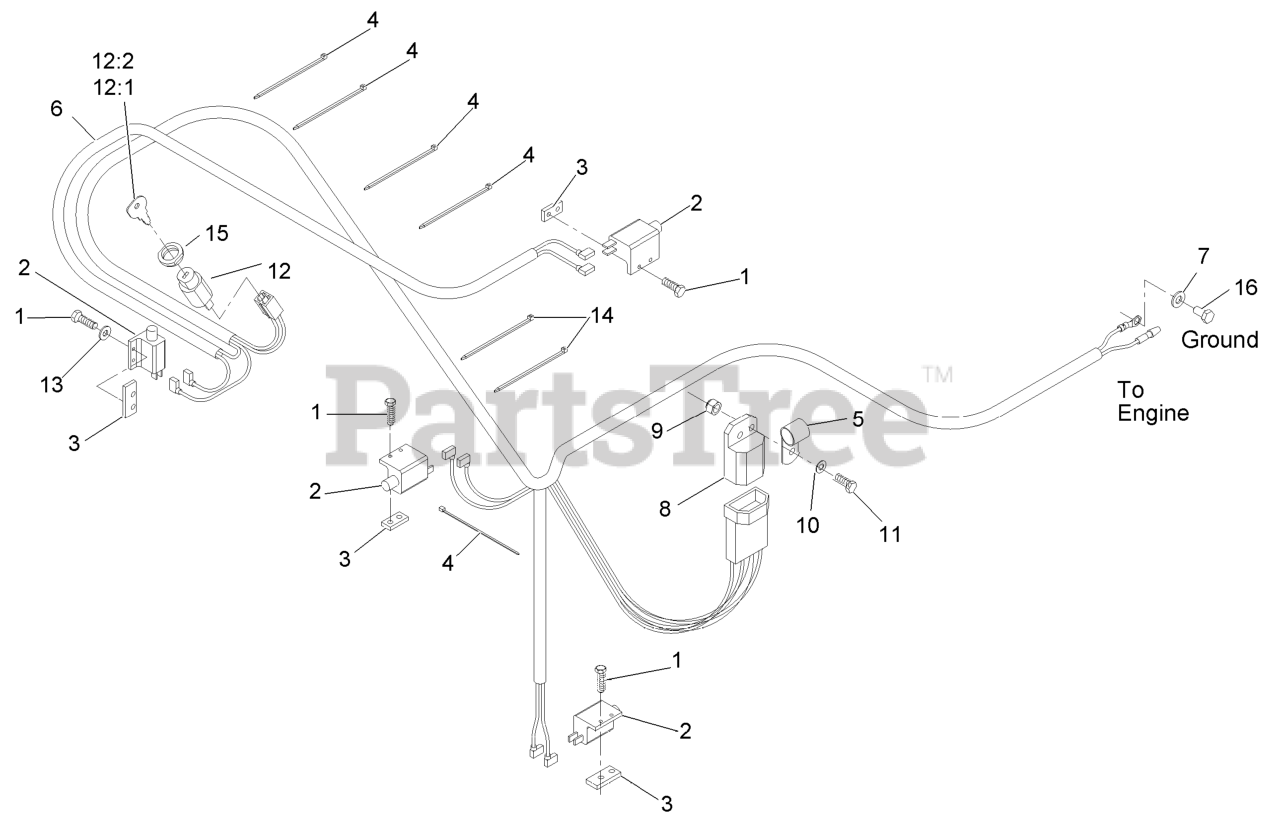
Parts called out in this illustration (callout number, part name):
1	SCREW-PPH
2	SWITCH-OPEN, NORMALLY
3	PLATE-TAPPED
4	TIE-CABLE
5	CLIP-LOOM
6	HARNESS,WIRING KA PULL ST
7	WASHER-PLAIN
8	MODULE-INTERLOCK
9	NUT-LOCK, NI
10	WASHER-FLAT
11	SCREW-HH
12	SWITCH & KEY (INCLUDES NU
12:1	KEYS-IGNITION (SPARE PAIR
12:2	KEY-IGNITION
13	WASHER-FLAT
14	TIE-PLASTIC
15	NUT-SWITCH, IGNITION
16	SCREW-HH
